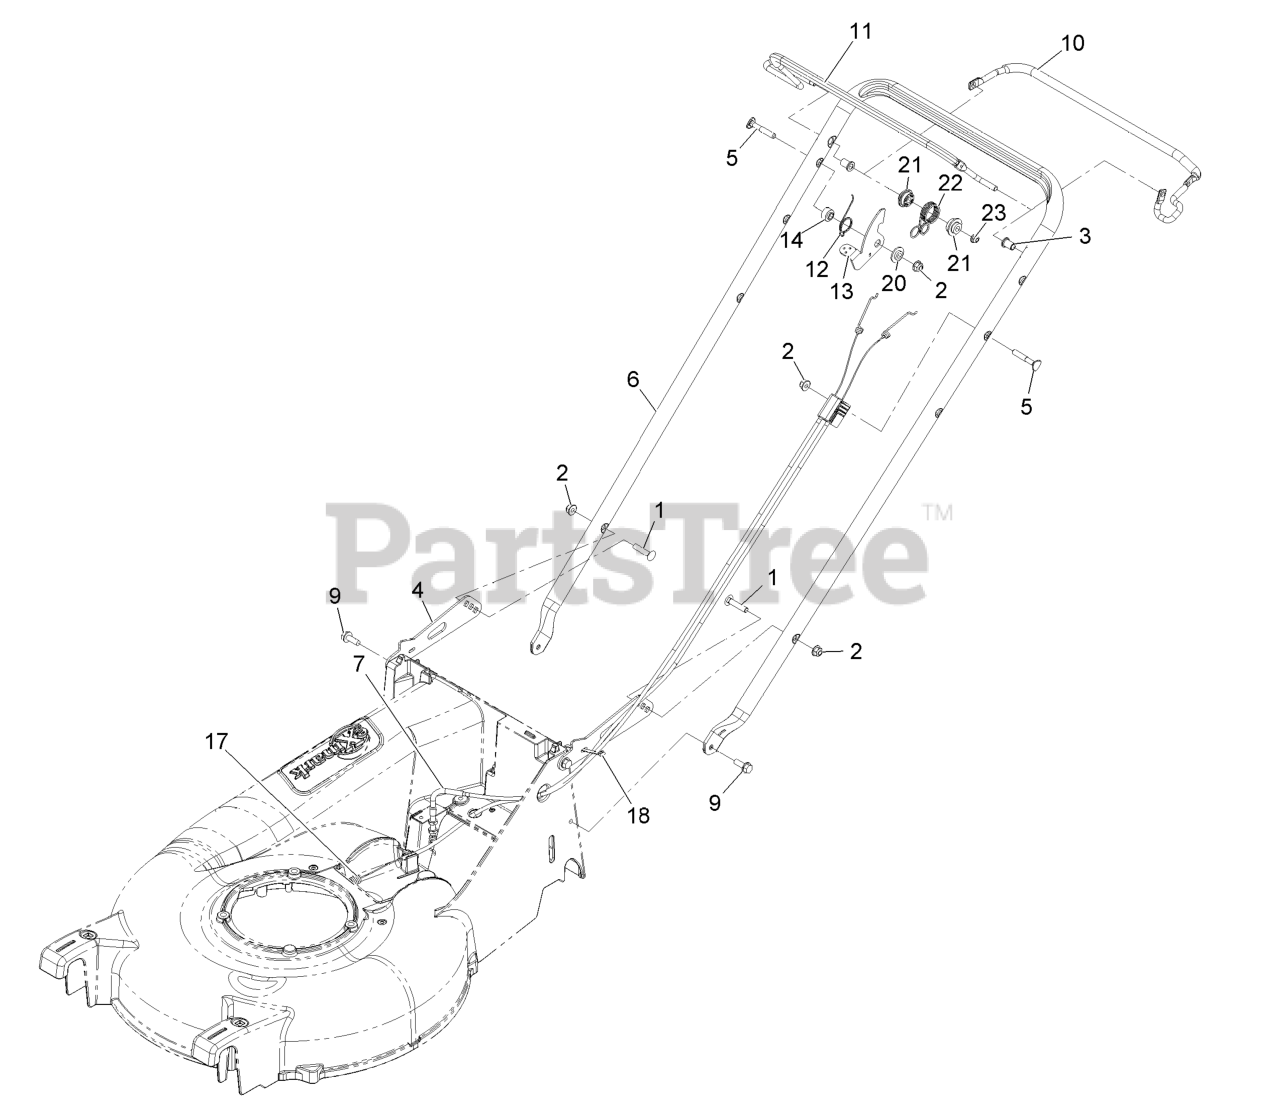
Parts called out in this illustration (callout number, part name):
1	BOLT-CARR
2	NUT-HF, NI
3	BUSHING-HANDLEBAR
4	BRACKET,HANDLEBAR
6	HANDLEBAR-P21
9	SCREW-TAPTITE
10	BAIL-DRIVE COATED
12	SPRING-LEVER, BBC
13	LEVER-BBC
14	BUSHING-STEPPED
17	CABLE-BBC
18	TIE-CABLE
20	WASHER-STEPPED
21	BUSHING-SPRING, PIVOT
22	SPRING,BBC RETURN
